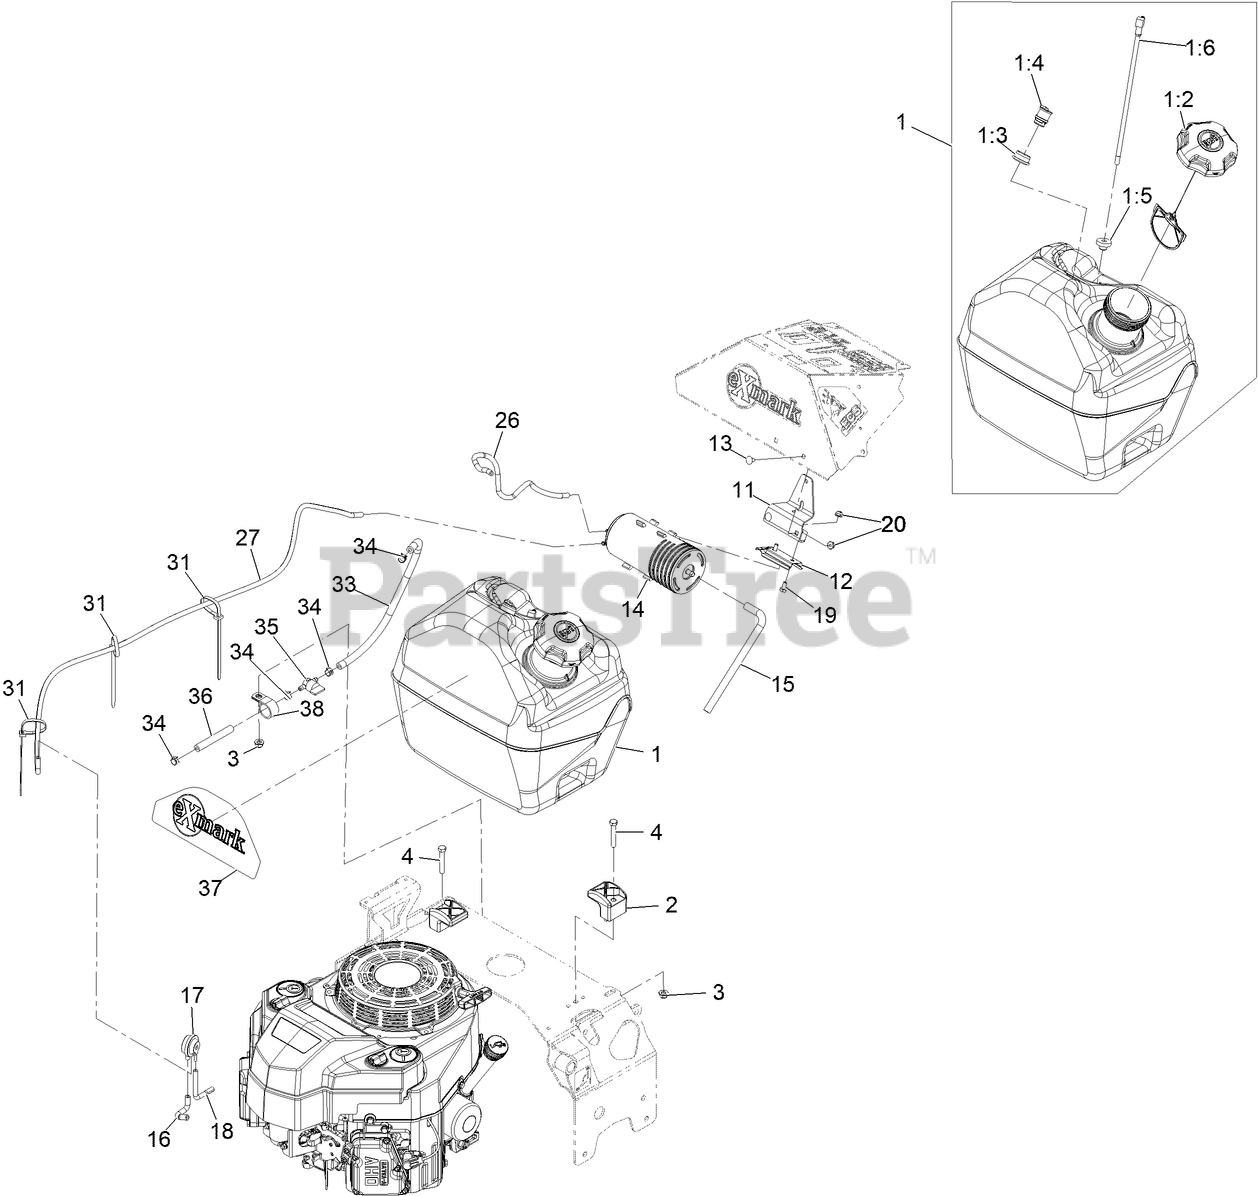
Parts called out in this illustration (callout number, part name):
1	Fuel Tank ASM, 5 Gal
1:2	CAP-FUEL, RATCHETING
1:3	GROMMET
1:4	VALVE-VENT, FUEL
1:5	BUSHING
1:6	FITTING, FUEL W/LINE AND SCREEN
3	NUT-HF, NI
4	SCREW-HH
11	BRACKET, MOUNTING PDM
12	BRACKET-CANISTER, CARBON
13	SCREW-CARR
14	CANISTER-CARBON, 800CC
15	HOSE-VENT, CANISTER
16	HOSE-VENT, FORMED
17	VALVE-CONTROL, VACUUM
18	HOSE-VENT, FORMED
19	SCREW-HH
26	HOSE-EMISSIONS
27	HOSE-VENT, FORMED
31	TIE-CABLE
33	HOSE-FUEL
34	CLAMP-HOSE
35	VALVE-FUEL
36	HOSE-FUEL
37	Artwork-Exmark Logo Fuel Tank
38	CLIP-LOOM
